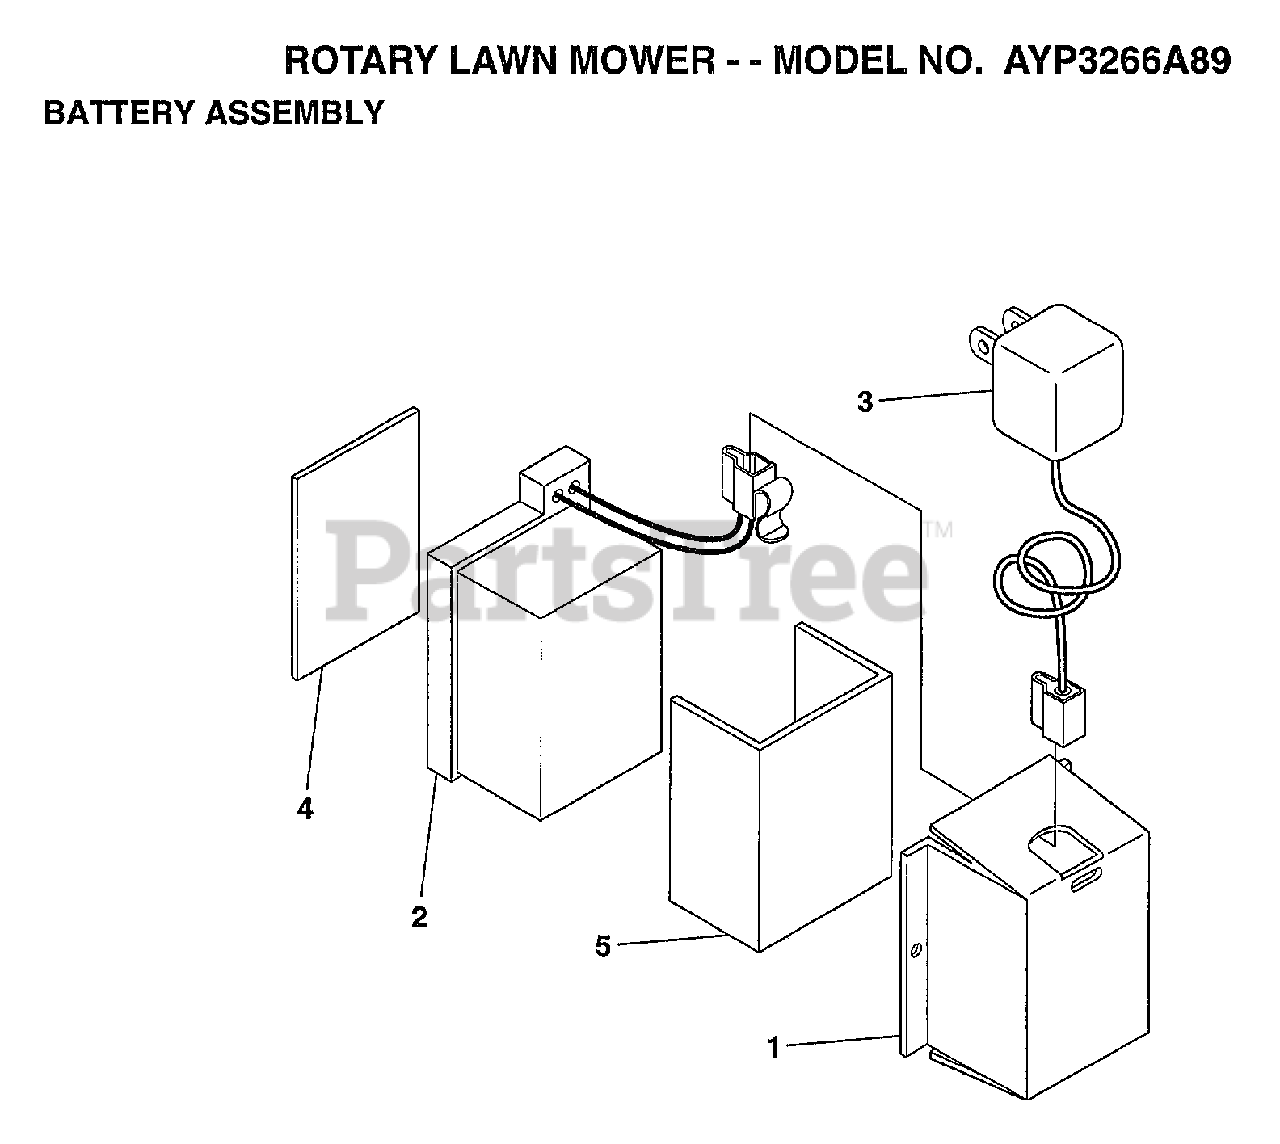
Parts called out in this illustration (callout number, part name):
1	BRACKET BATR'Y
3	CHARGER PM
4	"PAD PM, BATTERY"
5	"WRAP, BATTERY"
